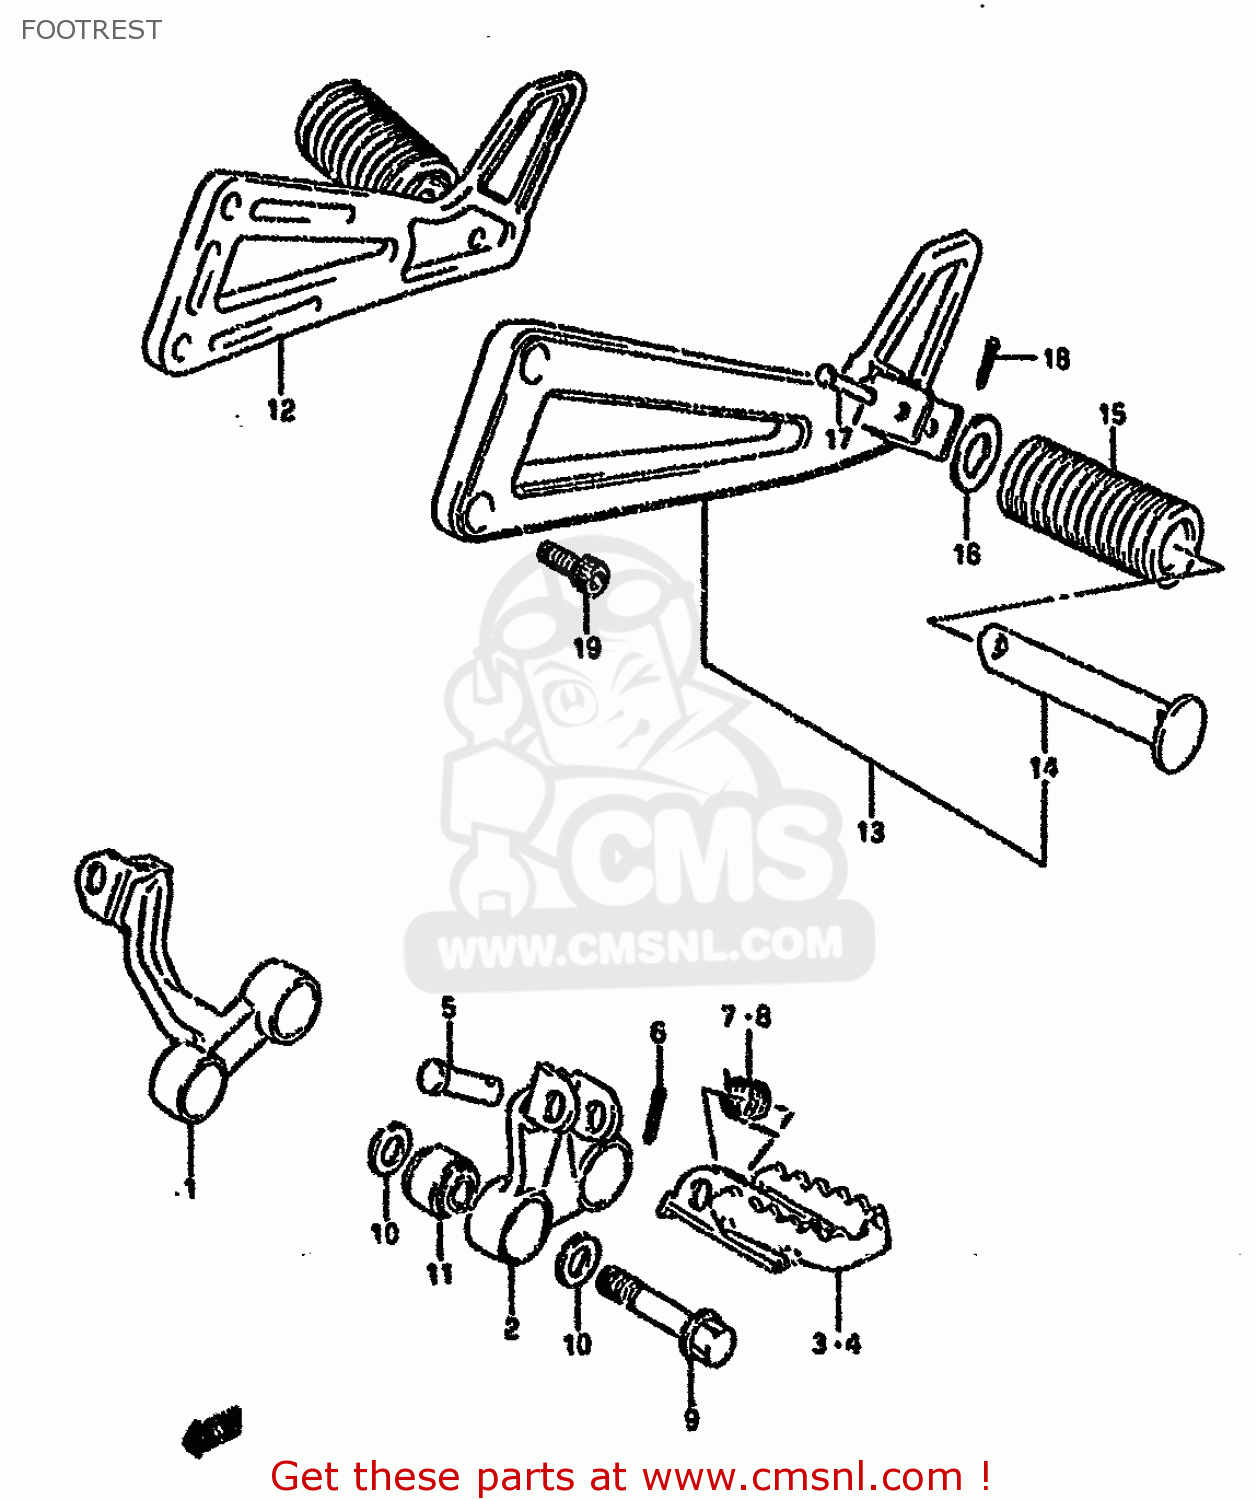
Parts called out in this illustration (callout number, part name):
1	BAR,FR FOOTREST,R
2	BRACKET,FR FOOTREST,L
3	FOOTREST,FR,R
4	FOOTREST,FR,L
5	PIN
6	PIN 20X20
7	SPRING
8	SPRING
9	BOLT(10X50)
10	WASHER
11	BUSH(10.2X25X19)
12	FOOTREST,PILLION RH
13	FOOTREST,PILLION
14	BAR,FOOTREST RUBBER
15	RUBBER,PILLION FOOTREST
16	WASHER (19.5X32X2)
17	PIN
18	PIN
19	BOLT
